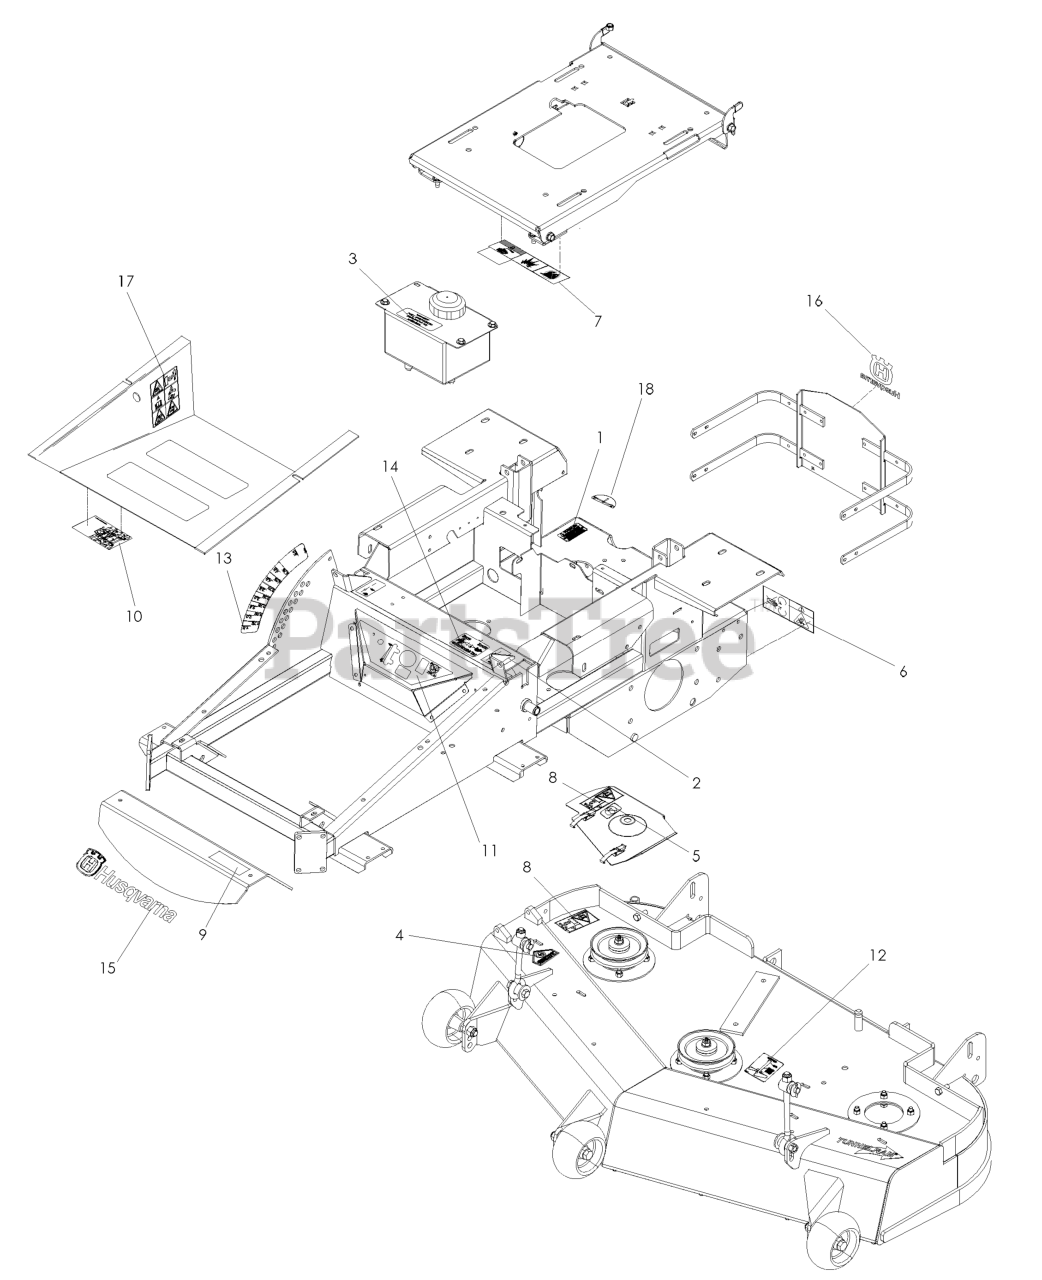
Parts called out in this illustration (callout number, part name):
1	DECAL, PROP. 65
2	DECAL, MOTION CONTROL
3	DECAL, OIL TANK
4	DECAL, CPSC
5	DECAL, NO STEP
6	DECAL, BELT DRIVE
7	EURO DECAL-BATTERY WARNIN6
8	DECAL, EURO SEVERING
9	DECAL, IZ4217
9	DECAL, IZ4819
9	DECAL, IZ4821
9	DECAL, IZ5223
9	DECAL, IZ5225
9	DECAL, IZ6125
9	DECAL, IZ25
9	SERVICE DECAL
10	DECAL, CONSOLE
11	DECAL, BELT ROUTING
12	DECAL, HEIGHT ADJ
13	DECAL, F.S.T.
14	DECAL, HUSQ 12" BLUE
15	DECAL, CROWN H 5-1/4 SILVER
16	DECAL, WARNING
17	DECAL, FUEL VALVE
